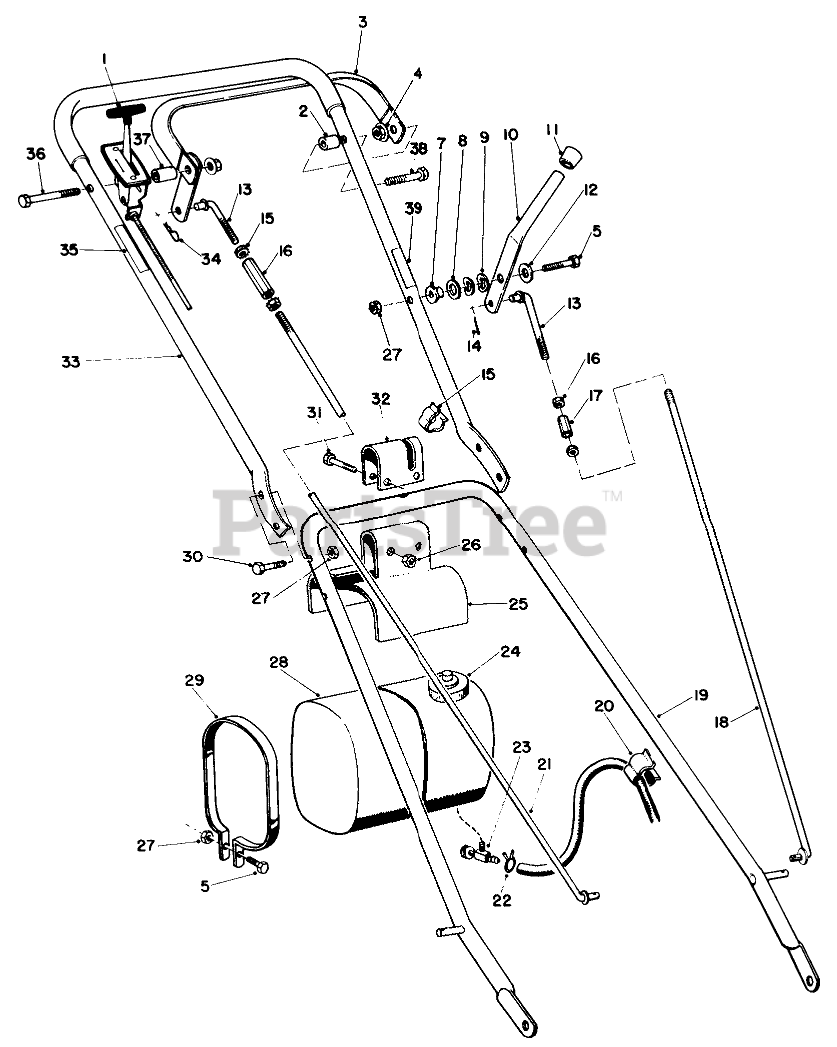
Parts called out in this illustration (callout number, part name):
1	Control, Throttle
2	Spacer
3	Control Bail
4	NUT-LOCK, HHF
5	SCREW-HH
7	PIVOT
8	WASHER-FLAT
9	WASHER-SPRING
10	CUTTER HANDLE R
11	Button Plug
12	WASHER-FLAT
13	LINK CONTROL ROD
14	PIN-COTTER
15	Clamp
16	NUT-KEPS
17	CONTROL ROD SLEEVE
18	CUTTER CONTROL ROD
19	LOWER HANDLE WA
20	CLAMP
21	CONTROL ROD
22	Clamp
23	.125 ID SHUTOFF VALVE
25	FUEL TANK BRACKET
26	Nut
27	NUT-LOCK
28	Tank
29	TANK STRAP
30	SCREW-HH
31	SCREW-HH
32	Clamp
33	Upper Handle
34	PIN-COTTER
35	Decal-Throttle
36	SCREW-HH
37	SLEEVE-PIVOT ROLLED
38	SCREW-HH
39	BLADE CONTROL DECAL
